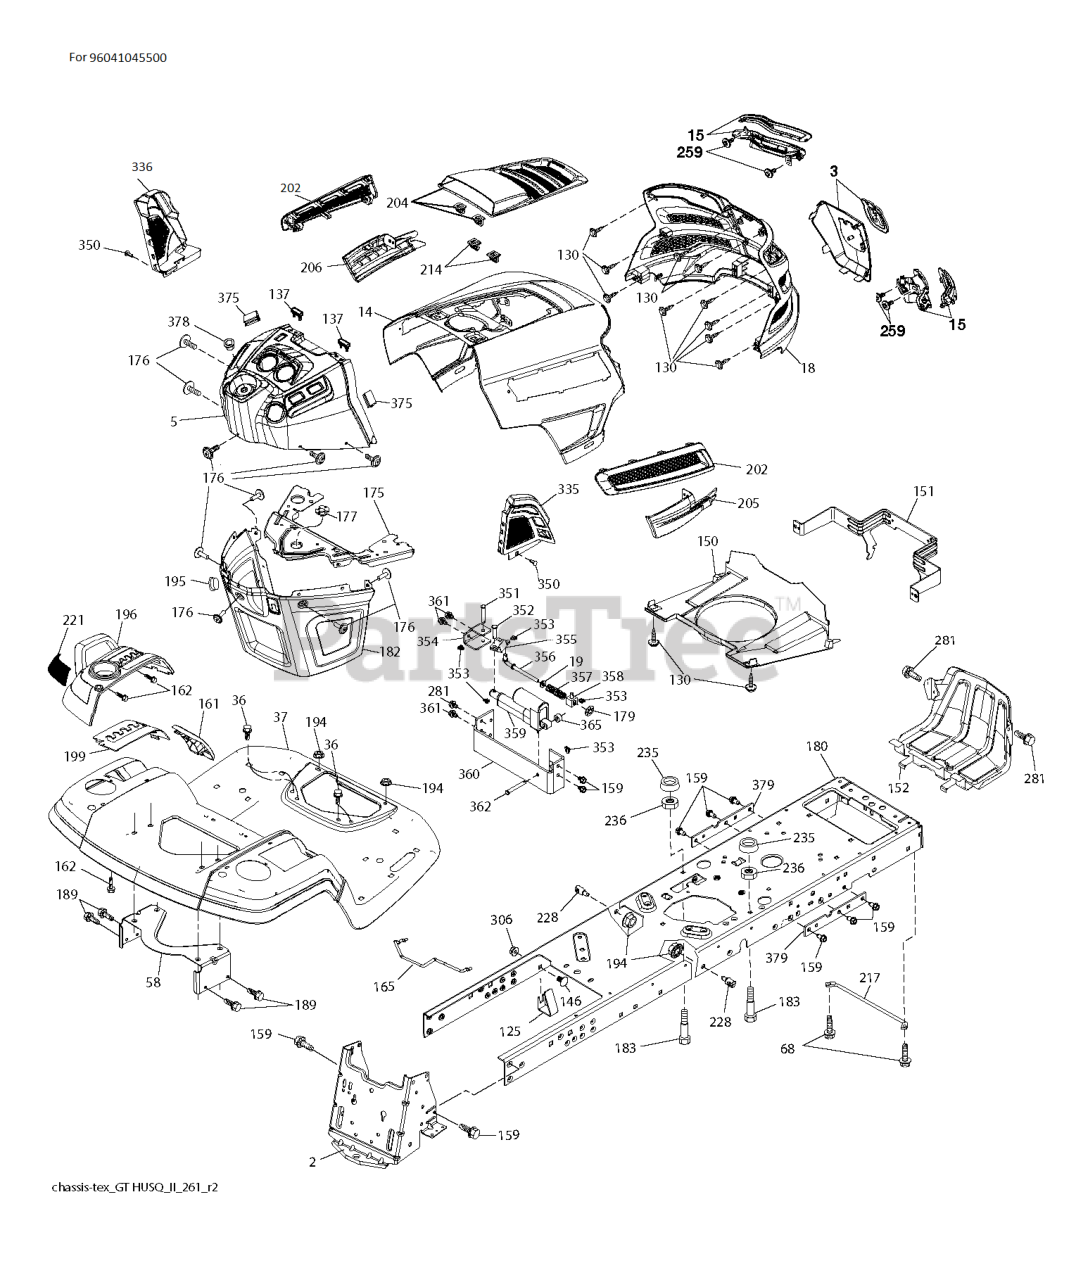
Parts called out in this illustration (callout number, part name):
2	DRAWBAR.STGT
5	DASH.UPR.GT2.DUAL.RD.PTO.MC
14	KIT.HOOD.ASM.HUSQ.GT.TEX.668
15	Service Kit
36	BOLT.5/16-18UNCX3/4 W/SEMS.BLK
37	FENDER.PNT.TX.GT.CH/FW/DL.HUSQ
58	BRKT.SUPPORT.FNDR/TANK
125	CLIP.FUEL.LINE
137	BUMPER DASH
146	BOLT.RDHD.SHT.SQNK.3/8-16X5/8
150	AIR.DUCT.GTV.BLACK
151	SERVICE KIT PIVOT BRACKET BRAC
152	SHIELD.BROWNING.PNT.GT.V2
159	SCREW, 3/8-16X3/4
161	CONSOLE.FUEL.WINDOW.HU
165	SUPPORT.TANK.REAR.B/TE
175	PLATE.PNT.CROSSMEMBER.HUSQ/PRE
176	SCREW.#10-24X5/8.RN.QU
177	BUSHING STEERING
180	CHASSIS LTGT BOLTED PAINTED X4
182	DASH.LOWER.COMMON.12V.ADAPTOR
189	BOLT.HEX.HD.WASHER.5/16-18X.75
195	PLUG.HOLE.DASH.LOWER.12V.BLK
196	SUBASM.CONSOLE.HUSQ.GT.DECKLFT
199	PLATE.DECK.LIFT.HUSQVARNA.GT
205	SIDE.TRIM.RH.GT.HUSQ.II
206	SIDE.TRIM.LH.GT.HUSQ.II.GRAY
214	CLIP.RETAINER.TINNER.
217	ROD.PIVOT.HOOD
221	REFLECTOR.LH.TEX GT HU
228	STUD.W/"D"ANTI-ROTATION
236	NUT.CENTERLOCK.5/16-
281	SCREW 3/8-16X1
306	NUT.HEX.FLANGE.3/8-16.LOCKNUT
335	COVER.LOWER.DASH.RH.BLACK
336	COVER-LH.LOWER.DASH.GT2.BLACK
350	CLIP.X-MAS.TREE
351	PIN.CLEVIS.375X2.125
352	CLEVIS.375X1.25
353	CLIP RETAINER
354	SUPPORT.DIFF.LOCK.BELLCRANK
355	BELLCRANK.PIVOT.LOCK.DIFF
356	LINK.LOCK.DIFF
357	SPRING.COMPRESSION
358	SWIVEL.GUIDE
359	ACTUATOR.ELECTRIC
360	BRACKET ACUATOR
362	CLEVIS.375 X 2.42
365	NYLN.SPCR.375 X .75 X .4375.L
375	BUMPER CLIP-ON. DASH 1"
378	BUSHING FLANGE; PLASTIC
379	CHASSIS.PLATE.REINFORCEMNT.431
